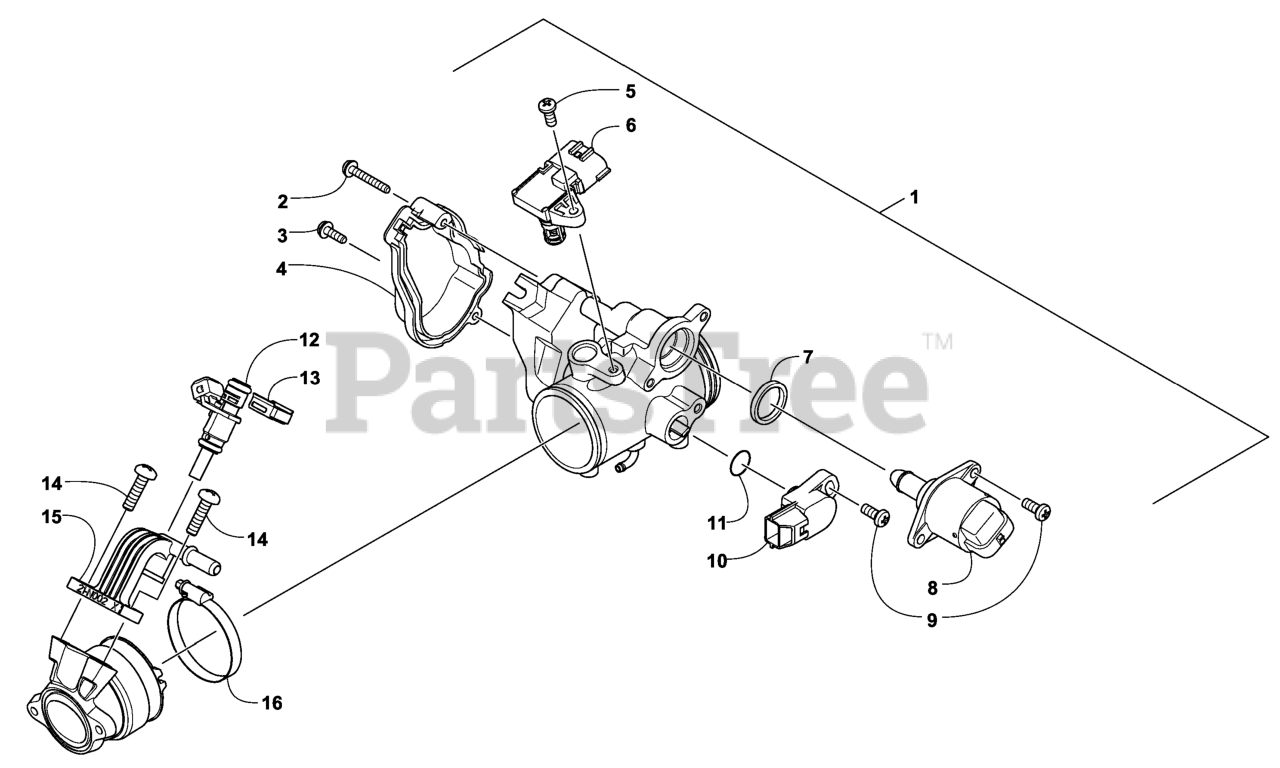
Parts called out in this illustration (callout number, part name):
1	THROTTLE BODY ASM
4	COVER-WIRE STAY
5	SCREW-WASHER
6	SENSOR-T MAP
7	SEAL-IDLE SPEED ACTUATOR
8	ACTUATOR-IDLE SPEED
10	SENSOR-THROTTLE POSITION
13	CLIP-INJECTOR
15	RAIL-FUEL
16	CLAMP-WORM, HOSE
